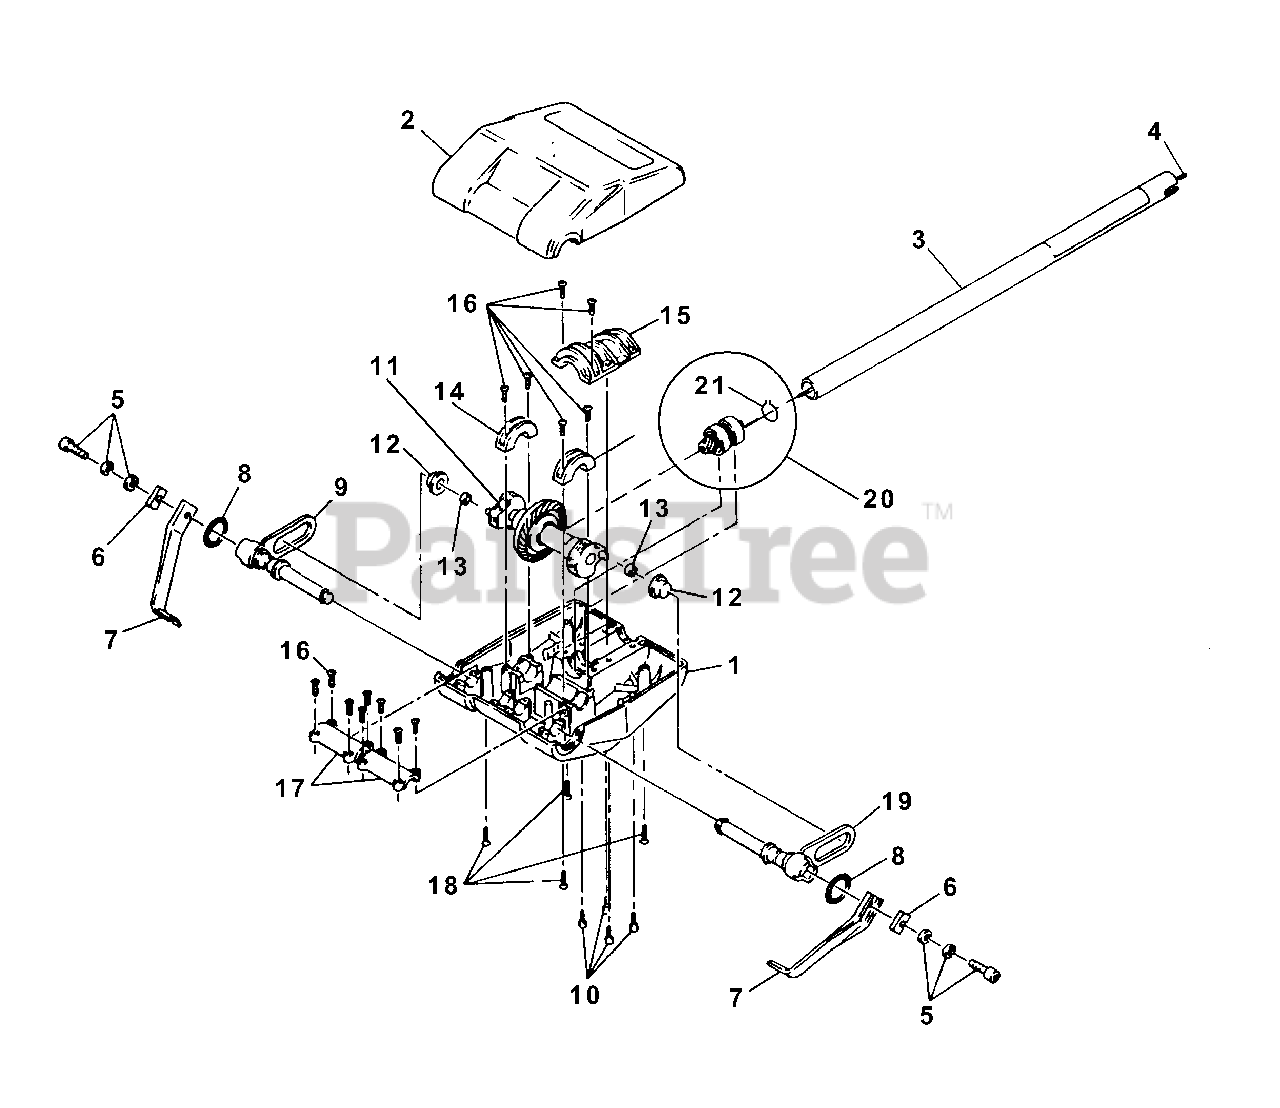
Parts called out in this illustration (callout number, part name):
1	LOWER COVER
2	UPPER HOUSING
3	DRIVESHAFT HOUSING
4	FLEX CABLE
5	BOLT-Sems (1/4 - 28 x 1")
6	SUPPORT-Tine
8	"O" RING
9	ROCKER ARM (L.H.)
10	SCREW, Thread Form (10-24 x 3/4")
11	CRANK ASSY.
12	FLOATING BUSHING
13	WASHER
14	CRANKSHAFT CLAMP
15	SHAFT CLAMP
16	SCREW, Thread Form (10-24 x 3/4")
17	SHAFT CLAMP
18	SCREW (8-16 x 1")
19	ROCKER ARM (R.H.)
20	PINNON GEAR & BEARING
21	SNAP RING
